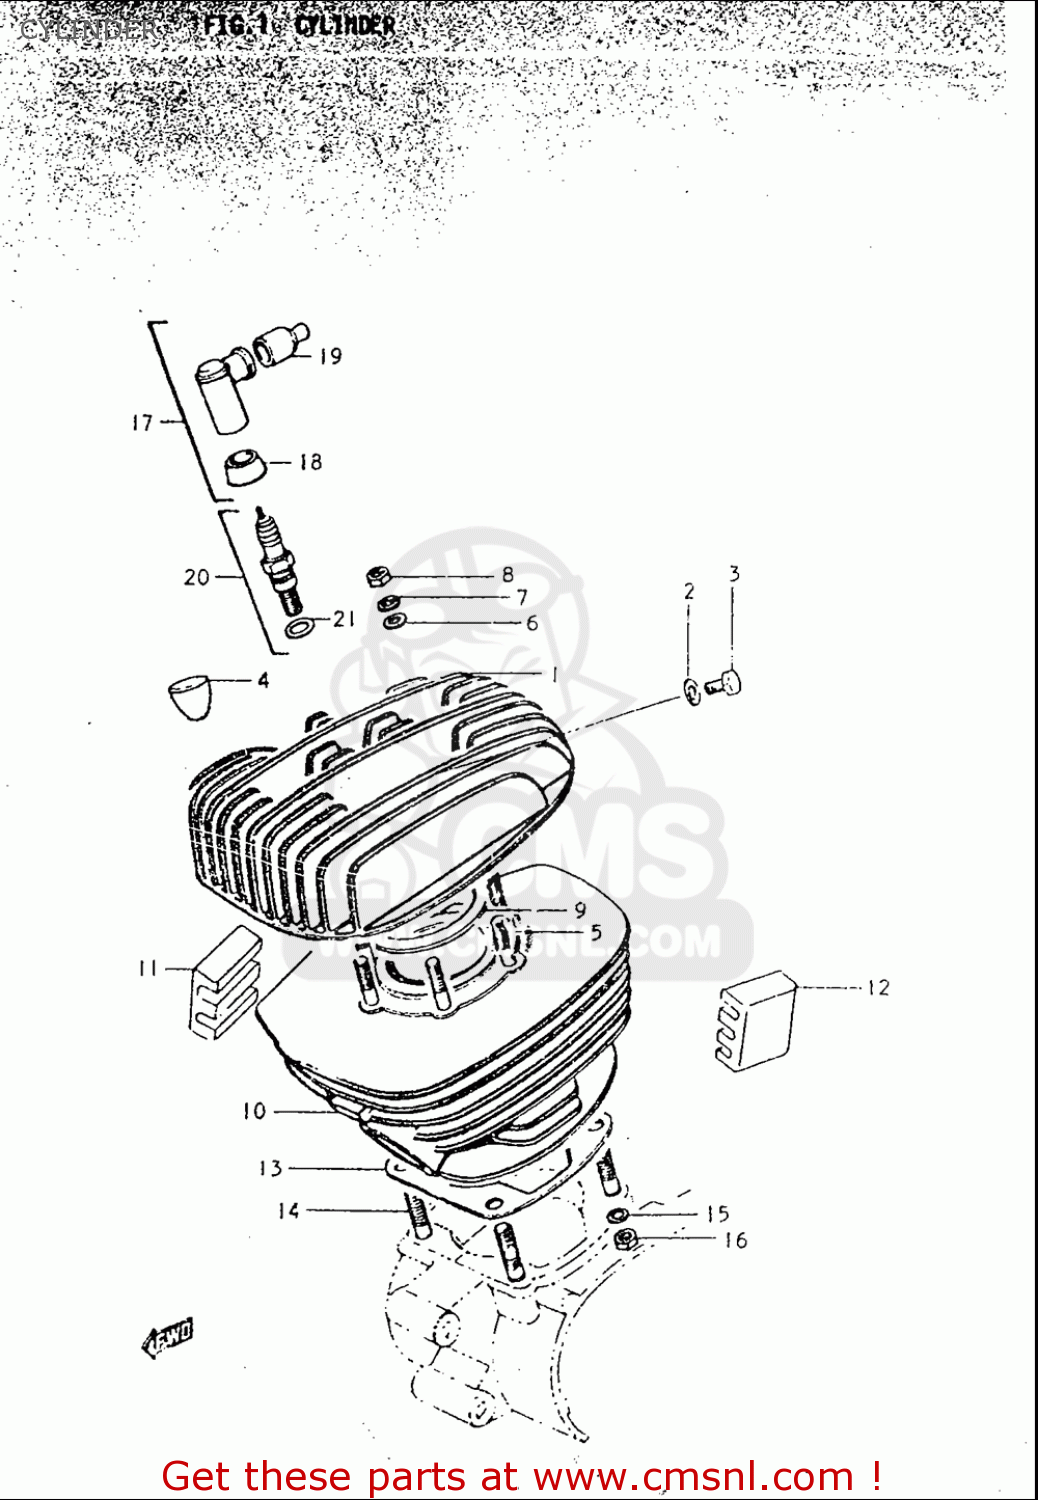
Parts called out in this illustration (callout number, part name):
2	GASKET(14X19.2X2) (NAS)
3	PLUG
5	BOLT,STUD
6	WASHER
7	WASHER,LOCK
8	NUT
9	GASKET,CYLINDER HEAD (NAS)
13	GASKET,CYLINDER
14	STUD 10X30
15	WASHER
16	NUT
20	PLUG,SPARK
21	GASKET(14X19.2X2) (NAS)
